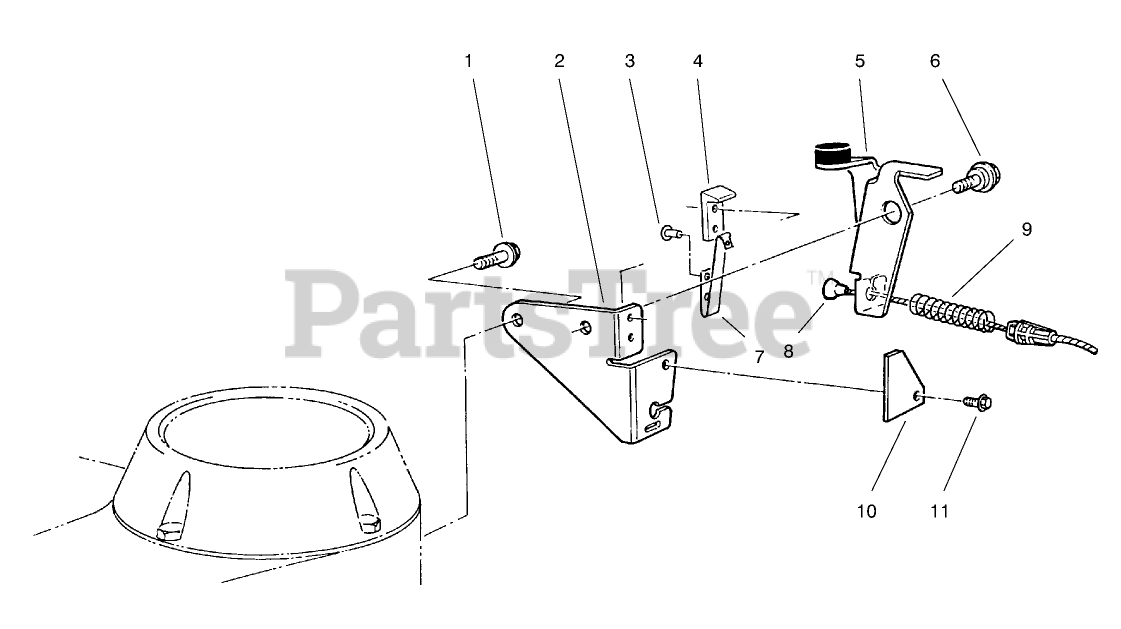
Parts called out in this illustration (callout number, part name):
1	SCREW-HWH
2	PLATE-BRAKE
3	RIVET-PLASTIC
4	STRAP-INSULATING
5	BRAKE PLATE ASM
6	SCREW-SHOULDER
7	STRAP-GROUND
8	BRAKE CABLE
9	SPRING-COMPRESSION
10	STOP-GROUND STRAP
11	SCREW-HWH
